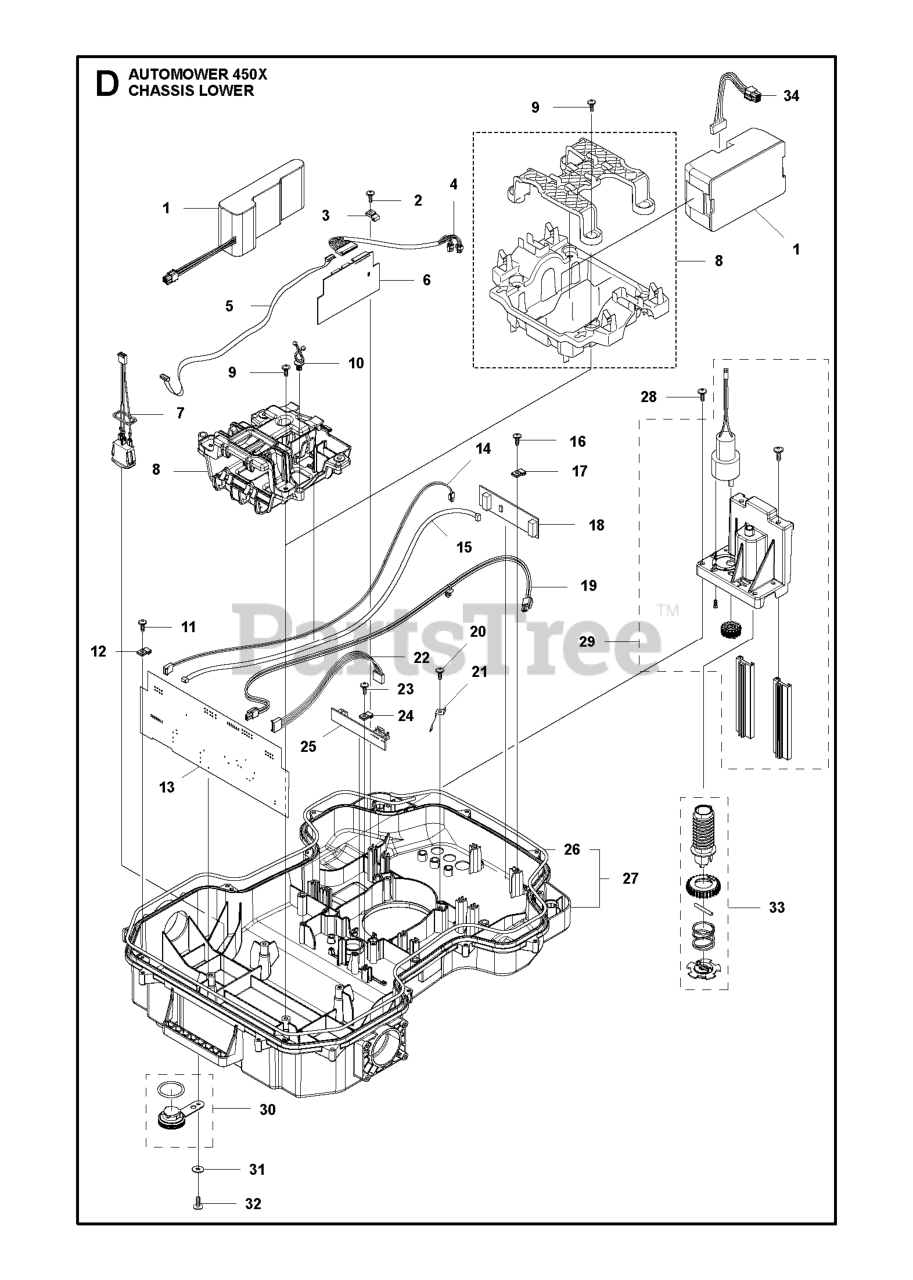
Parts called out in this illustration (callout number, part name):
1	BATTERY
1	BATTERY 588146401 PACKED
2	SCREW 14MM
3	CLAMP PCB
4	LOOM ULTRA SONIC EXTENSION
5	LOOM AUX
6	PRINTED CIRCUIT ASSY ULTRASONI
7	LOOM ON/ OFF
8	HOLDER KIT BATTERY
8	HOLDER BATTERY
9	SCREW ITXPANT
10	HOLDER TWIST LOCK
11	SCREW 14MM
12	CLAMP PCB
13	PRINTED CIRCUIT ASSY PCBA MAIN
14	WIRING ASSY LED LIGHT EXTENSIO
15	LOOM LOOP SENSOR
16	SCREW 14MM
17	CLAMP PCB
18	PRINTED CIRCUIT ASSY LOOP SENS
19	LOOM CHARGING LINK HIGH CHARGI
20	SCREW 14MM
21	SPRING GUIDE HEIGHT ADJUSTMENT
22	LOOM HEIGHT ADJUSTMENT
23	SCREW 14MM
24	CLAMP PCB
25	PRINTED CIRCUIT ASSY PCBA CUTT
26	SEALING STRIP
27	CHASSIS KIT LOWER
28	SCREW 14MM
29	MOTOR ASSY HEIGHT MOTOR
30	PLUG KIT
31	WASHER
32	SCREW ITXPANT
33	SCREW KIT
34	WIRING ASSY BATTERY CABLE
